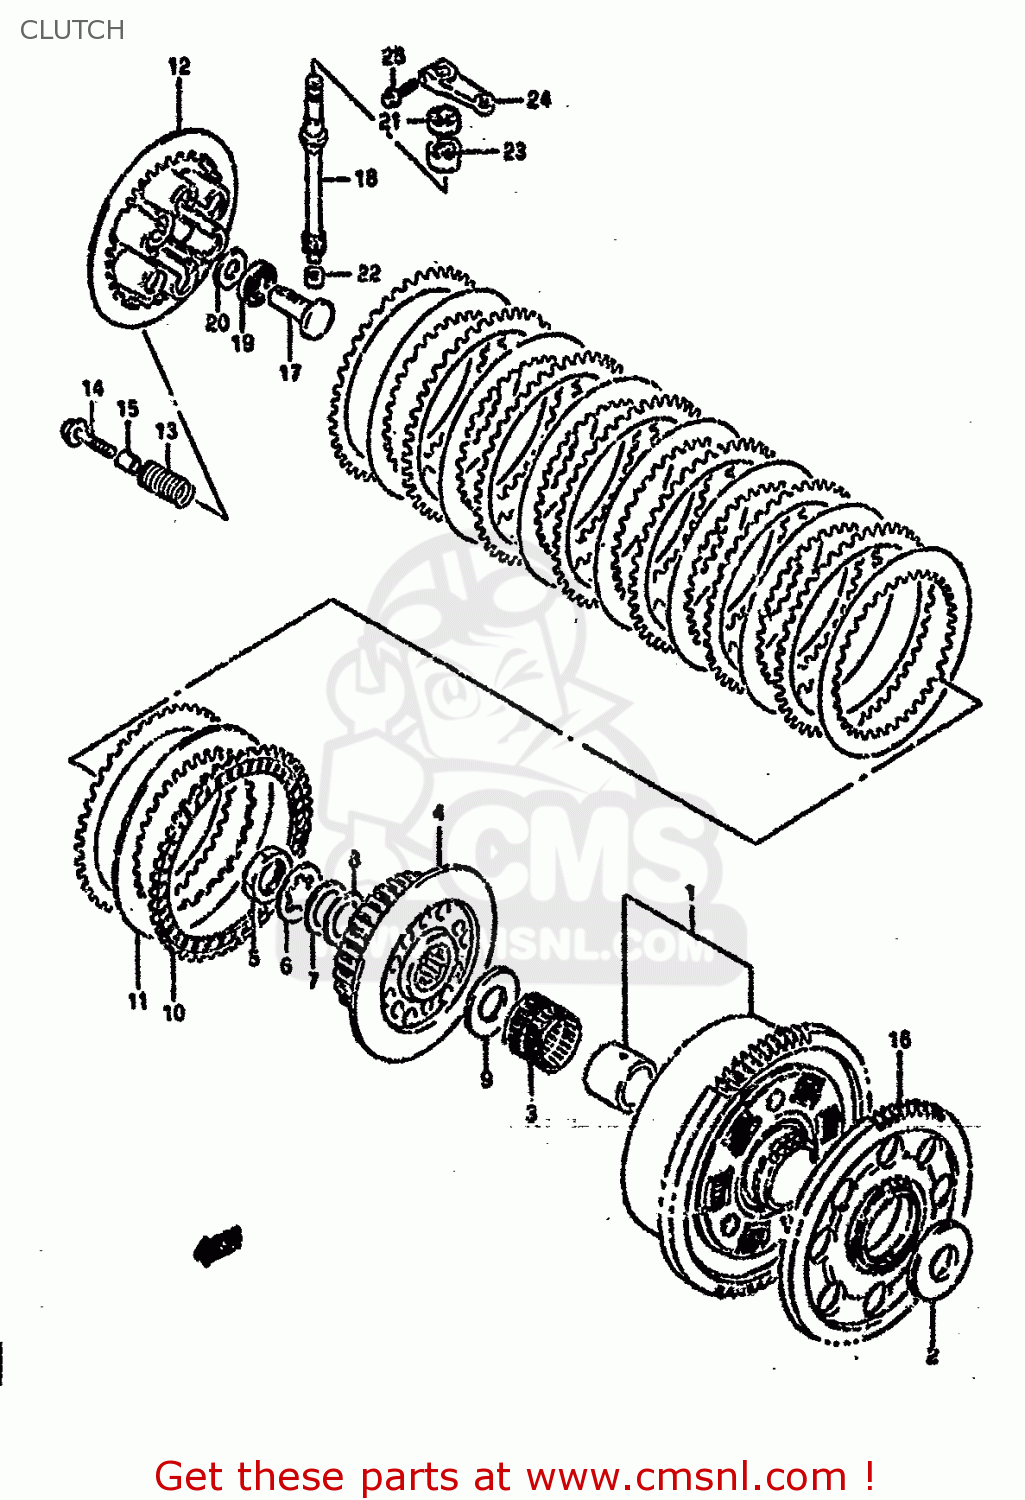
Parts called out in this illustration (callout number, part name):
1	GEAR ASSEMBLY,PRIMARY DRIVE
2	WASHER(25X54X2.5)
3	BEARING(35X40X35.8)
4	HUB,CLUTCH SLEEVE
5	NUT
6	WASHER,LOCK
7	WASHER
8	WASHER
9	WASHER(25X50X2.5)
10	PLATE,CLUTCH DRIVE (NAS)
11	PLATE,CLUTCH DRIVEN (NAS)
12	DISC,CLUTCH PRESSURE
13	SPRING
14	BOLT(6X40)
15	SPACER(6.2X12X18)
16	GEAR,GENERATOR DRIVE
17	RACK,CLUTCH RELEASE
18	PINION,CLUTCH RELEASE
19	BEARING(15X28X2)
20	WASHER(15.5X28X1)
21	OIL SEAL
22	BEARING 10X14X10
23	BEARING(15X22X12)
24	ARM,CLUTCH RELEASE
25	BOLT
